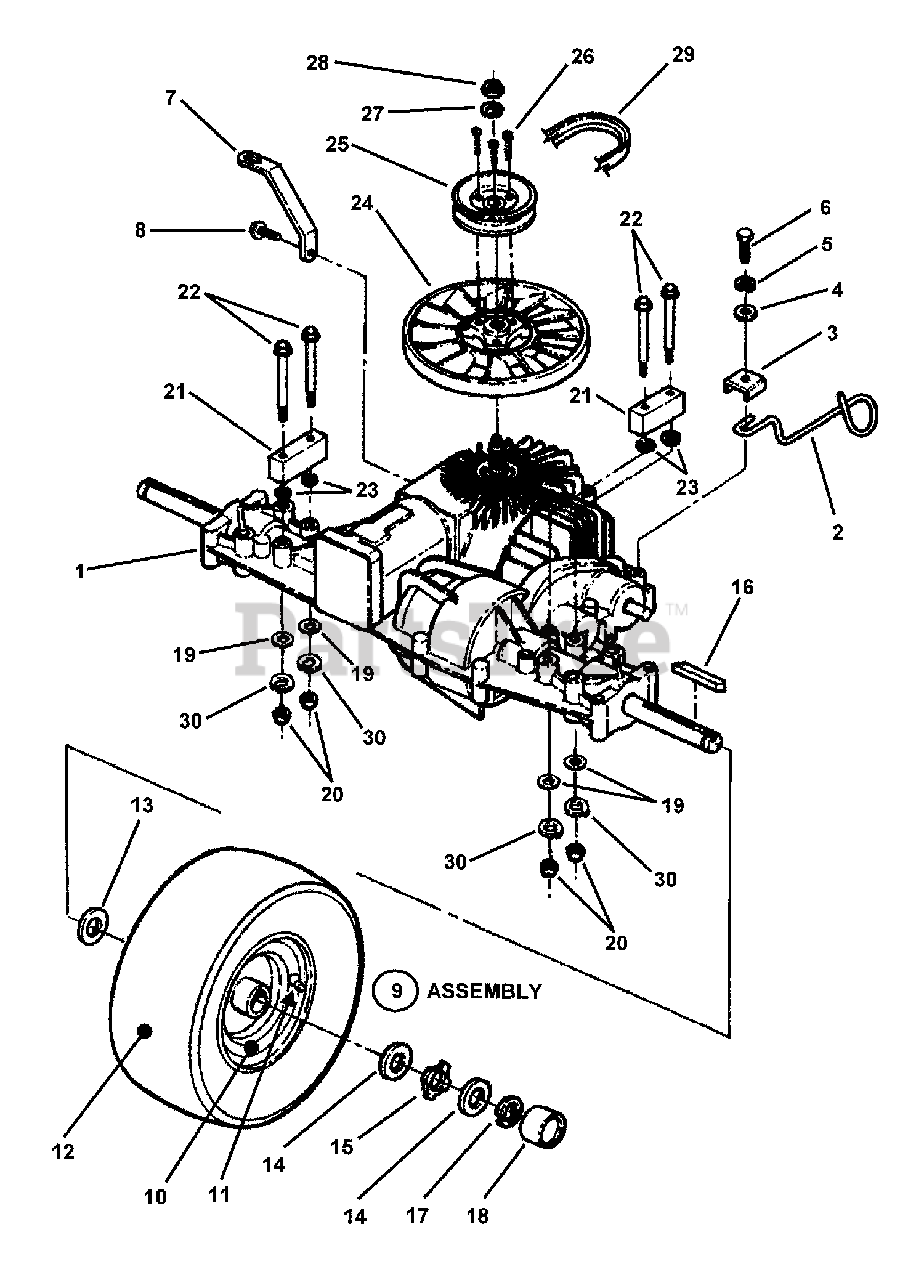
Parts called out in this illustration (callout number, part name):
1	TRANSMISSION, Hydro
2	RELEASE LEVER, Hydro
3	RETAINER, Release Lever
4	WASHER, 1/4" I.D. x 1" O.D. x 1/16" Thick, Flat
5	WASHER, 1/4" Split Lock
6	BOLT, 1/4-28 x 1/2" Hex Head Cap, Grade 5
7	STRAP, Torque
8	BOLT, 5/16-18 x 5/8" Hex Washer Self-Tap (Swage)
9	ASSEMBLY, Rear Wheel
10	RIM, 16 x 7.50
11	VALVE STEM
12	TIRE, 16 x 7.50-8 Rear Turf
13	WASHER, 3/4" I.D. x 1-1/2" O.D. x 1/8" Thick, Flat
14	WASHER, 3/4" I.D. x 1-5/16" O.D. 1/16" Thick, Flat
15	WASHER, Hub Cap Retaining
16	KEY, 3/16" Square x 2-1/2" Long
17	RING, 3/4" Retaining
18	HUB CAP
19	WASHER, .344 I.D. x 11/16 O.D. x 1/16" Thick Flat
20	NUT, 5/16-18 Hex, Grade 5 or B
21	BLOCK, Hydro Spacer
22	SCREW, 5/16-18 x 3-3/4" Hex Head Cap
23	RETAINER, 5/16" Bolt
24	ASSEMBLY, Hydro Cooling Fan
25	PULLEY, Hydro Drive
26	SCREW
27	WASHER, Lock
28	NUT
29	BELT, Engine to Hydro (Effective Length 28.814" HA Section)
30	WASHER, 5/16 Split Lock
